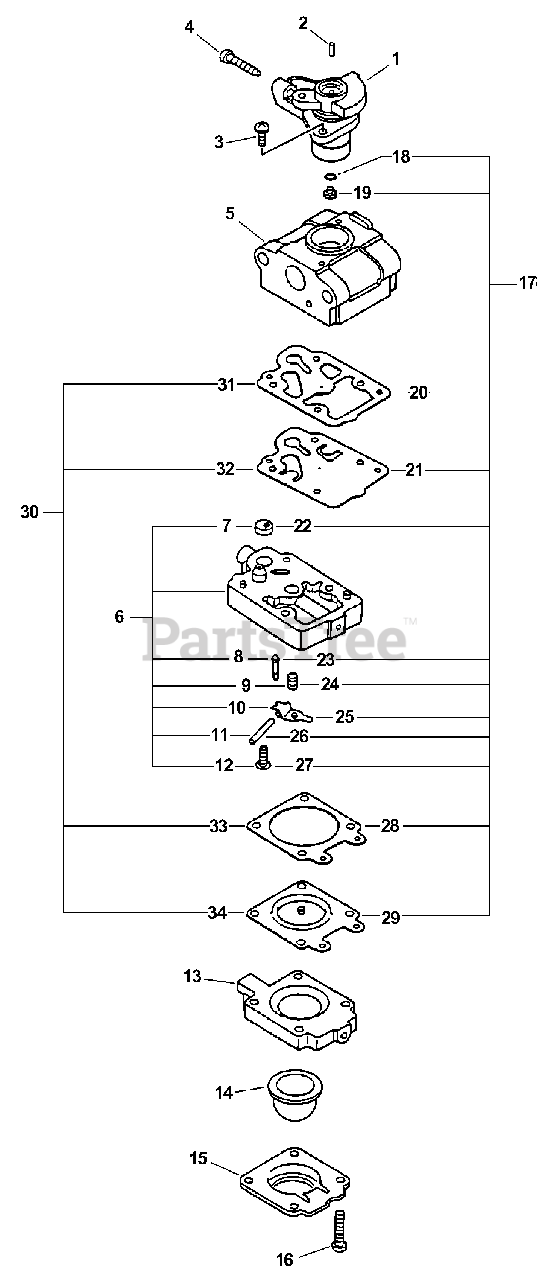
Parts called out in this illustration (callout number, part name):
1	THROTTLE VALVE ASSY
2	CAP, LIMITER
4	SCREW, IDLE ADJUST
5	BODY, CARBURETOR
6	BASE, PURGE
7	STRAINER
8	VALVE, INLET NEEDLE
9	SPRING, METERING LEVER
10	LEVER, METERING
11	PIN, METERING LEVER
12	SCREW, METERING LEVER PIN
13	PURGE BASE ASSY
14	BULB, PURGE
15	RETAINER, PURGE BULB
16	SCREW, PUMP COVER
17	REPAIR KIT
18	O-RING
19	JET
20	GASKET, PUMP
21	DIAPHRAGM, PUMP
22	STRAINER
23	VALVE, INLET NEEDLE
24	SPRING, METERING LEVER
25	LEVER, METERING
26	PIN, METERING LEVER
27	SCREW, METERING LEVER PIN
28	GASKET, DIAPHRAGM
29	DIAPHRAGM, METERING
30	DIAPHRAGM/GASKET KIT
31	GASKET, PUMP
32	DIAPHRAGM, PUMP
33	GASKET, DIAPHRAGM
34	DIAPHRAGM, METERING
